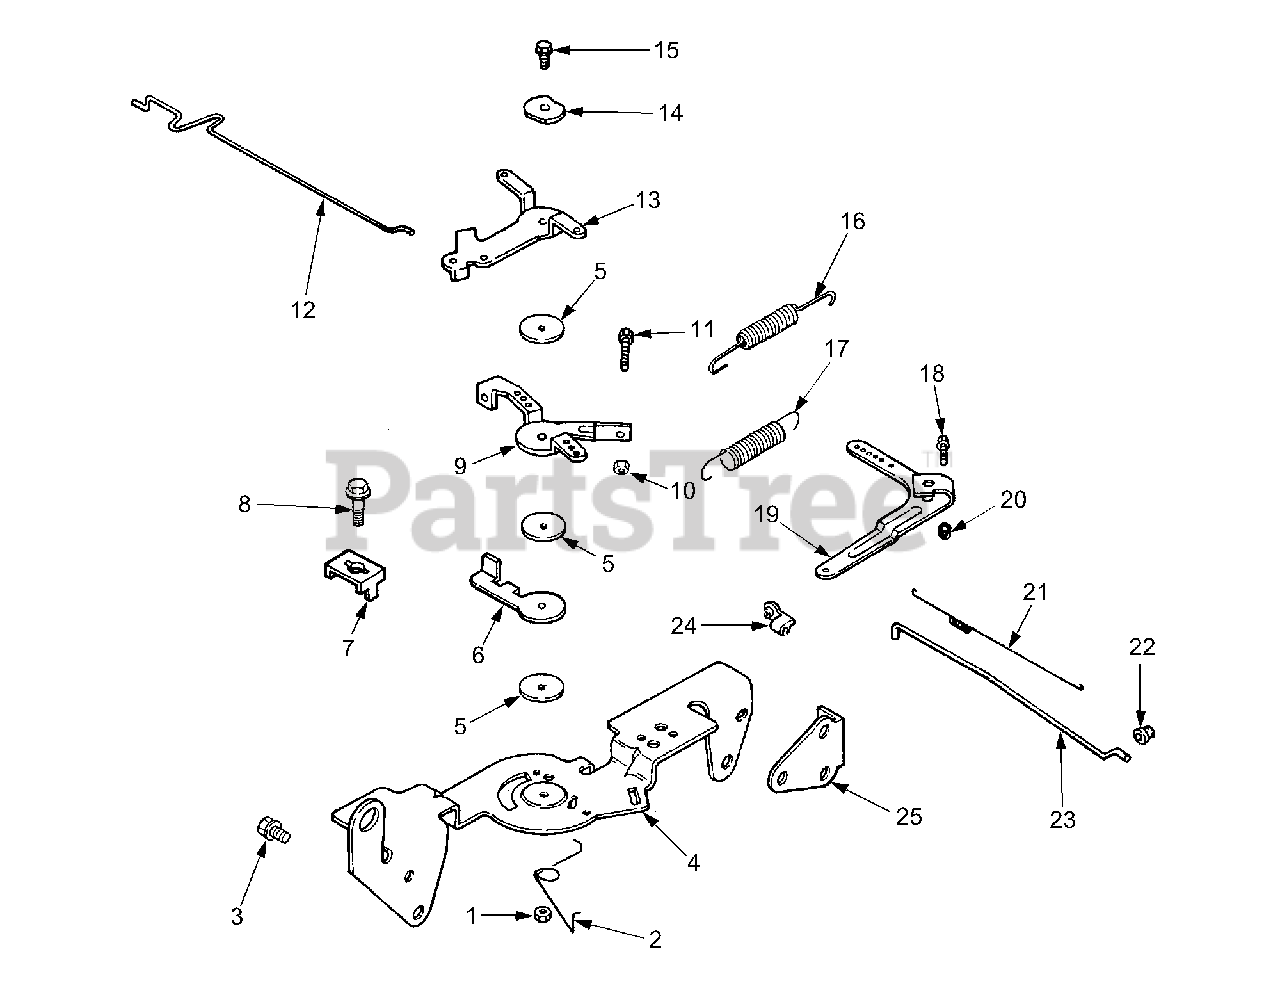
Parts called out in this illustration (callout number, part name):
1	Nut, Hex Lock M5 x 0.8
2	Spring, Choke Return
3	Screw, Hex Flange M6 x 1.0 x 16
4	Bracket, Control
5	Washer, Plain 5.5 mm
6	Lever, Throttle Actuator
7	Clamp,Cable,
8	Screw, Hex Flange M5 x 0.8 x 16
9	Lever, Throttle Control
10	Nut, Hex M4 x 0.7.
11	Screw, Hex Cap M4 x 0.7 x 30
12	Linkage,Choke
13	Lever, Choke
14	Washer, Spring 1/4"
15	Screw, Hex Flange M5 x 0.8 x 20
16	Spring, Throttle Limiter
17	Spring, Governor
18	Screw, Carriage
19	Lever, Governor
20	Nut, Hex Flange M6 x 1.0"
21	Spring, Linkage
22	Bushing, Linkage Retaining
23	Linkage, Throttle
24	Bushing, Linkage Retaining
25	Bracket Support
